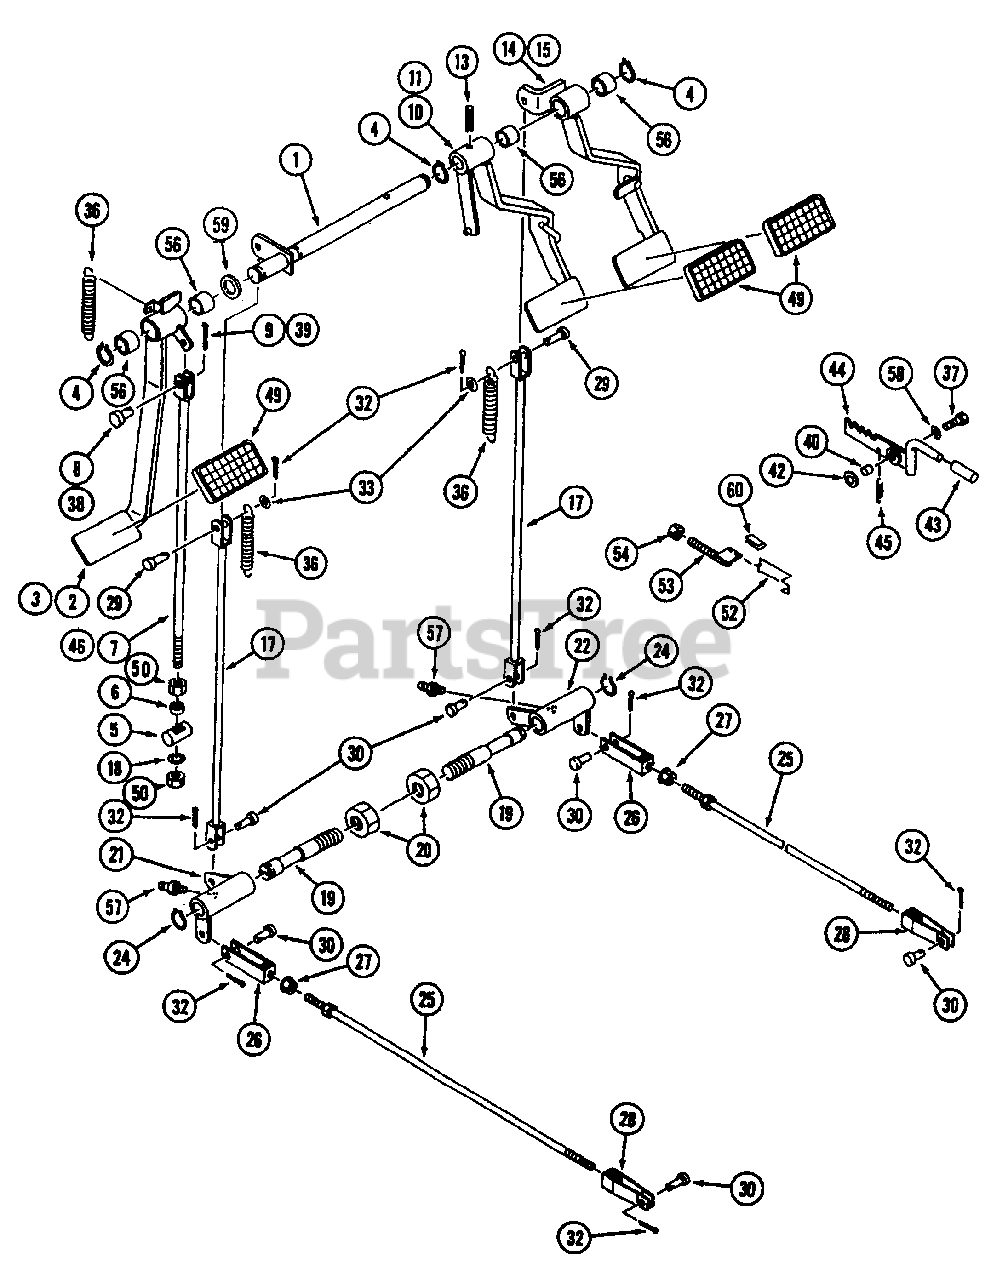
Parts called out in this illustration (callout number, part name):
2	Pedal, Clutch
3	Pedal, Clutch
10	Pedal, Brake L.H.
11	Pedal, Brake L.H.
14	Pedal, Brake R.H.
15	Pedal, Brake R.H.
21	Link, Brake L.H.
22	Link, Brake R.H.
38	Pin, Clevis
39	Pin, Split
44	Lever, Parking
46	Rod, Clutch
52	Hook, Clutch Pedal
53	Bolt, Stopper
57	Nipple, Grease
